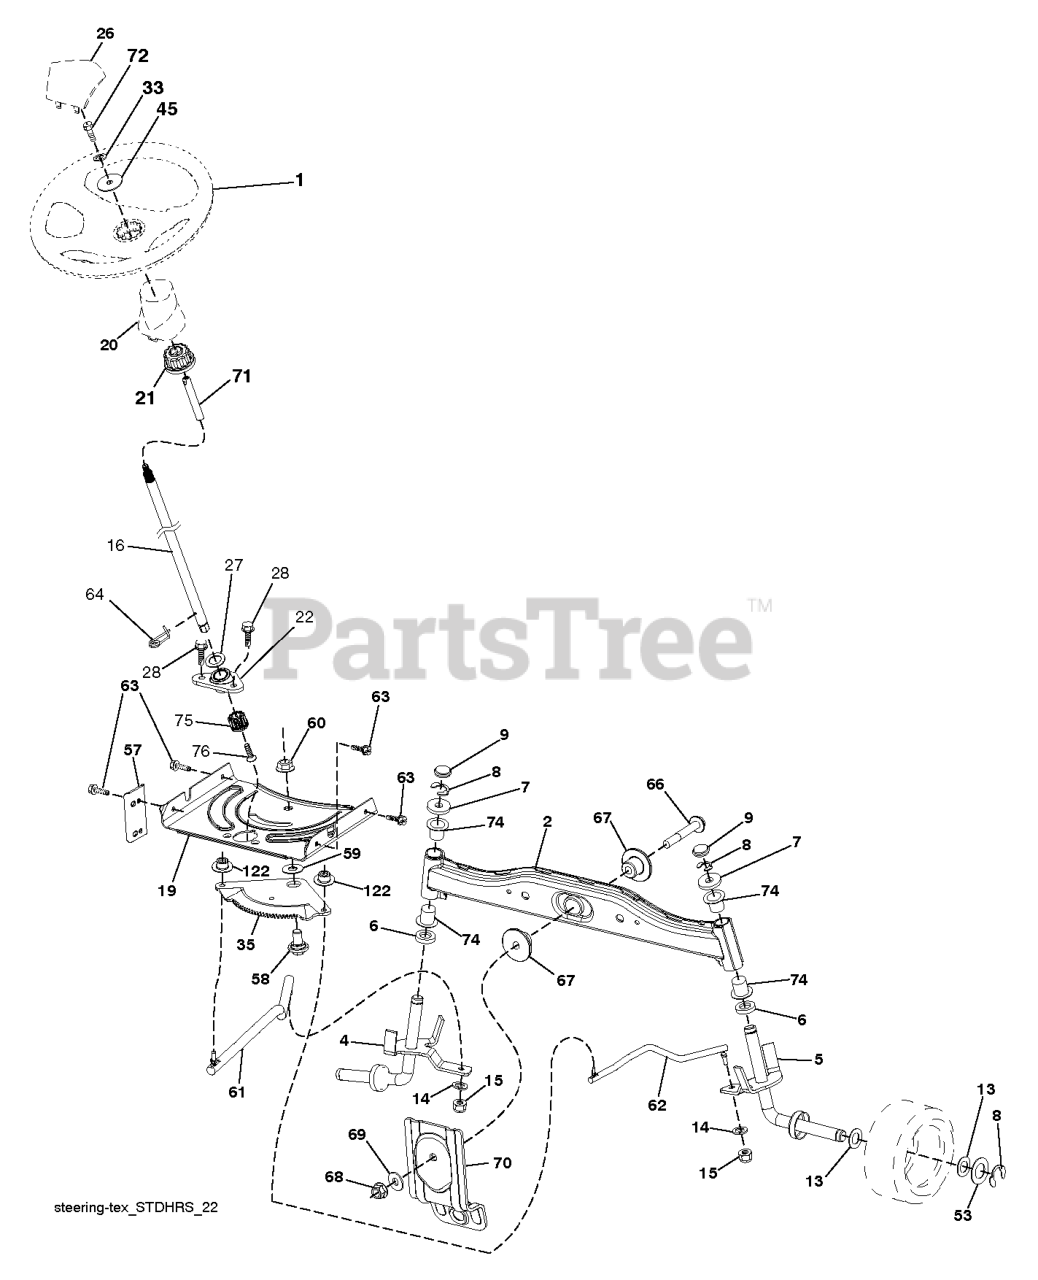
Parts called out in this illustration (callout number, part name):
1	WHEEL.STEER.HUSQ.SR.498.OVMLD
2	AXLE HALF ASM-WELDED
4	SPINDLE.STEERING.ASM.LH.13".TI
5	SPINDLE.STEERING.ASM.RH.13".TI
6	THRUST WASHER
9	CAP.SPINDLE.BLACK
14	WASHER, LOCK 3/8
15	NUT CROWNLOCK 3/8-24
16	SHAFT.STEER.3/4.PLATED.TEX
19	PLATE.STEER.DDL.NLT/NG
20	STEERING.BOOT.HUSQ.LT
21	ADAPTER, WHEEL STNG..
22	STEERING.SUPT.LOWER.
26	INSERT.CAP.WHL.STRG.HUSQ.PREM
28	SCREW, 3/8-16X3/4
33	WASHER.LOCK.HVY.HLCL.SPR.5/16
35	GEAR.SECTOR.PLATE.DDL.
45	WASHER.11/32
53	WASHER.HARDENED
57	BRACKET.UPSTOP.TEX
58	BOLT.SHOULDER.SECTOR.P
59	WASHER.THURST.SECTOR.S
60	NUT FLANGE LOCK 5/8-11
61	DRAGLINK.LH.BALLSTUD.D
62	DRAGLINK.RH.BALLSTUD.D
63	SCREW
64	RETAINER.CLIP.SPRING.S
66	BOLT HEX FGHD 7/16-14 X 3 SERR
67	BUSHING.PM.FRONT AXLE
68	NUT.LOCK.FLANGE.7/16
69	WASHER.1.5X.505X.118
70	BRACKET.SUSP.MWR.FRT.30"SRD
71	SHAFT.EXTEN.STRG.SPLINE
72	BOLT 5/16-18 X 4 W/PATCH
74	BRNG T
122	CAP.GEAR.SECTOR.TEX
